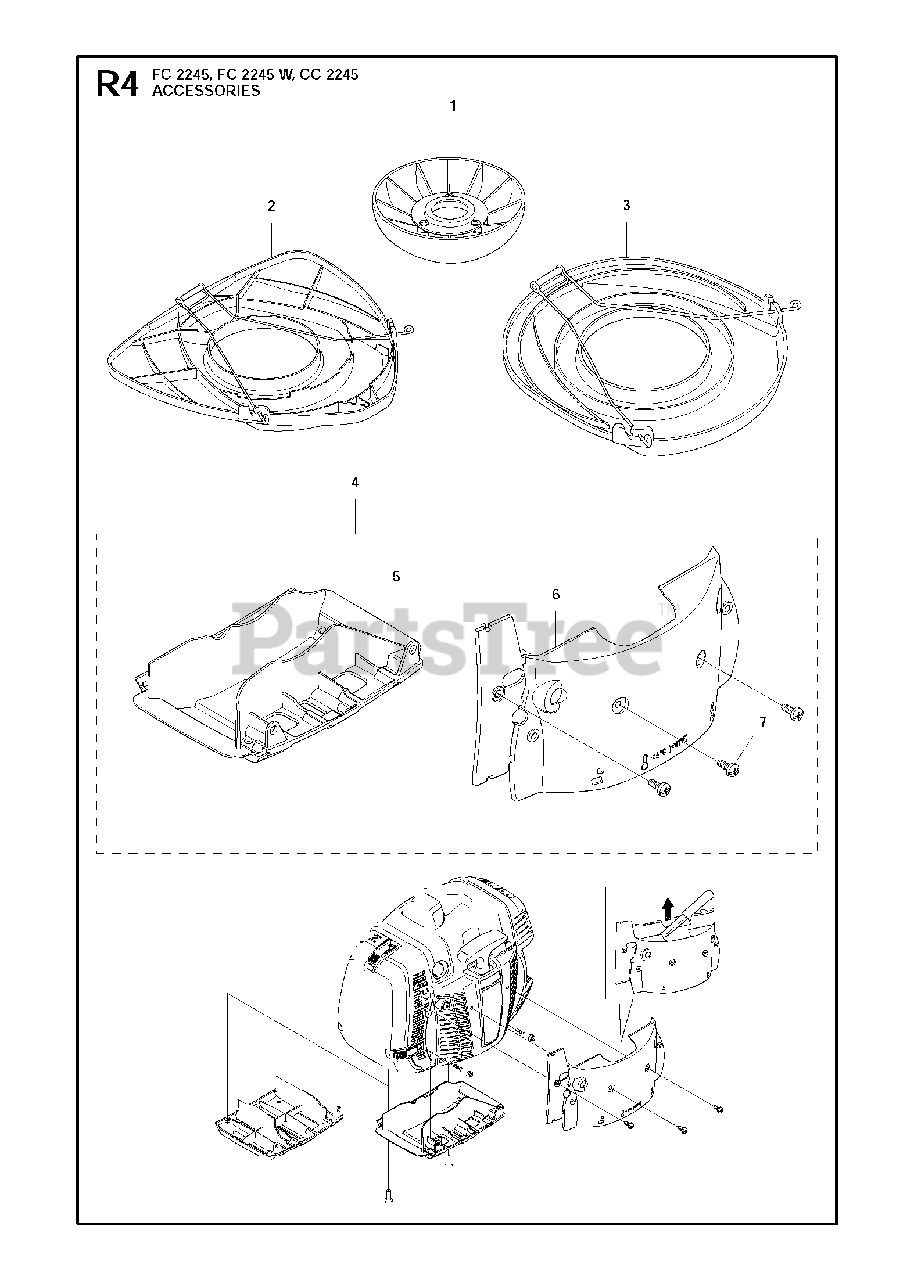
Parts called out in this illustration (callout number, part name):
1	SUPPORTING CUP
2	TRANSPORT GUARD
3	BLADE GUARD TRANSPORT
4	WINTER KIT
5	PROTECTIVE COVER
6	WINTER COVER
7	SCREW
